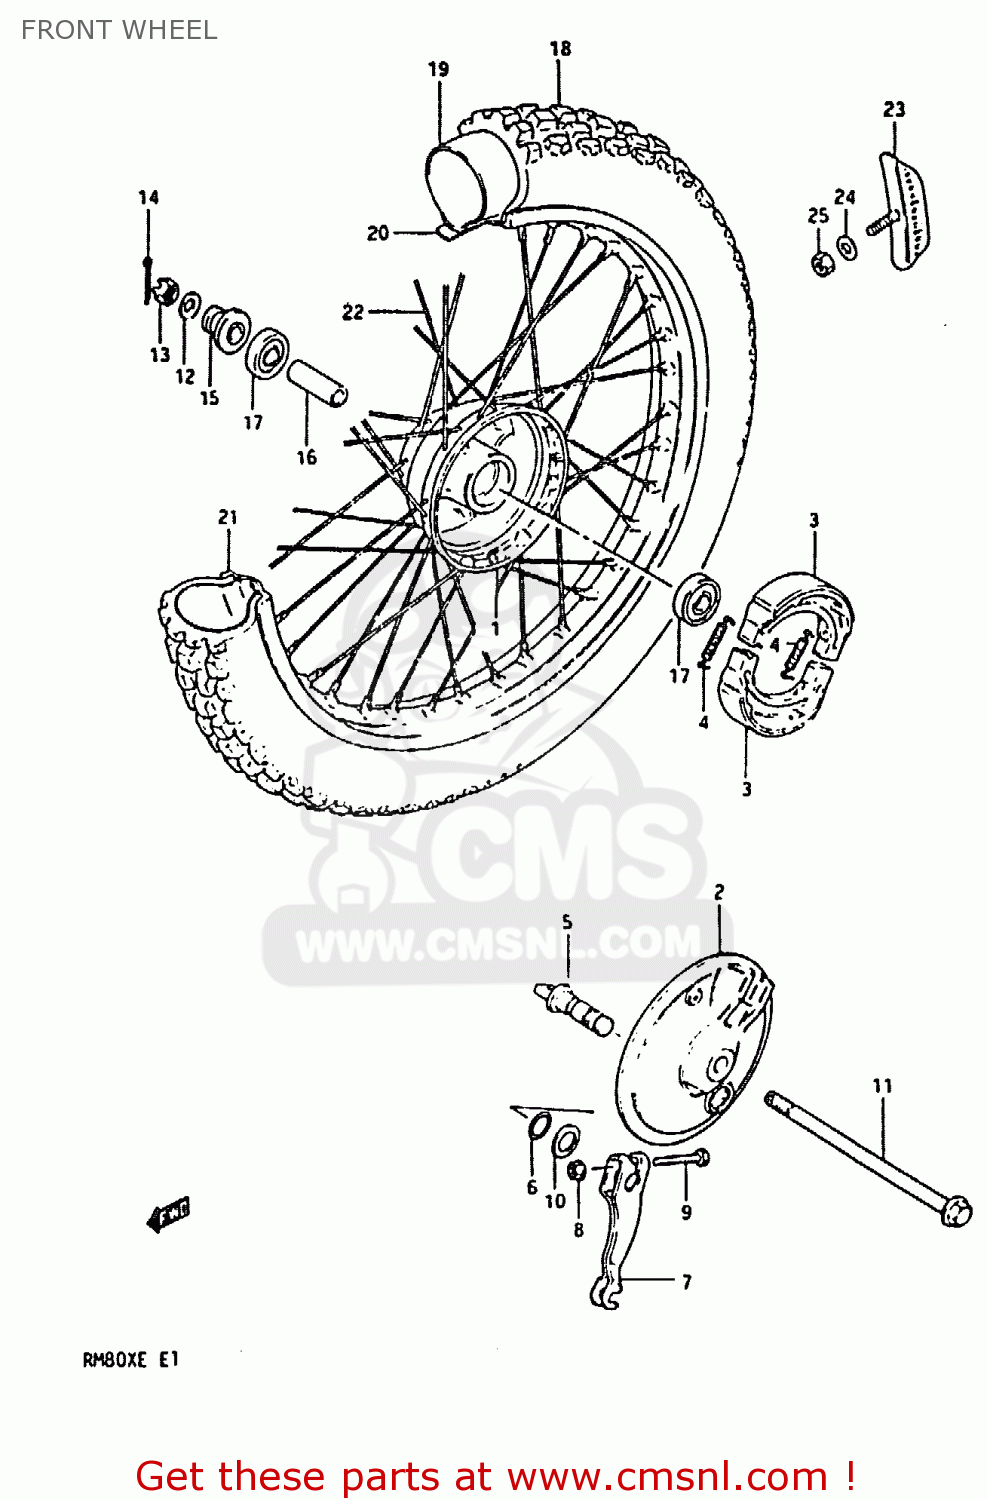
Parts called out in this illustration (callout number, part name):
1	HUB,FRONT
2	PANEL,FRONT HUB
3	SHOE,BRAKE (MCA)
4	SPRING(L:35.8)
5	CAM,BRAKE
6	O RING(D:2.5,ID:11.4)
7	LEVER,FRONT BRAKE CAM
8	NUT
9	BOLT
10	WASHER(12.5X20X1)
11	AXLE,FRONT
12	WASHER
13	NUT
14	PIN 20X20
15	SPACER,FRONT AXLE,RIGHT
16	SPACER (10.4X15X48)
17	BEARING
18	TIRE,FRONT
19	TUBE,INNER
20	PROTECTOR,WHEEL,INNER
21	RIM,FRONT WHEEL
22	SPOKE SET,FRONT
23	STOPPER,BEAD
24	WASHER
25	NUT
